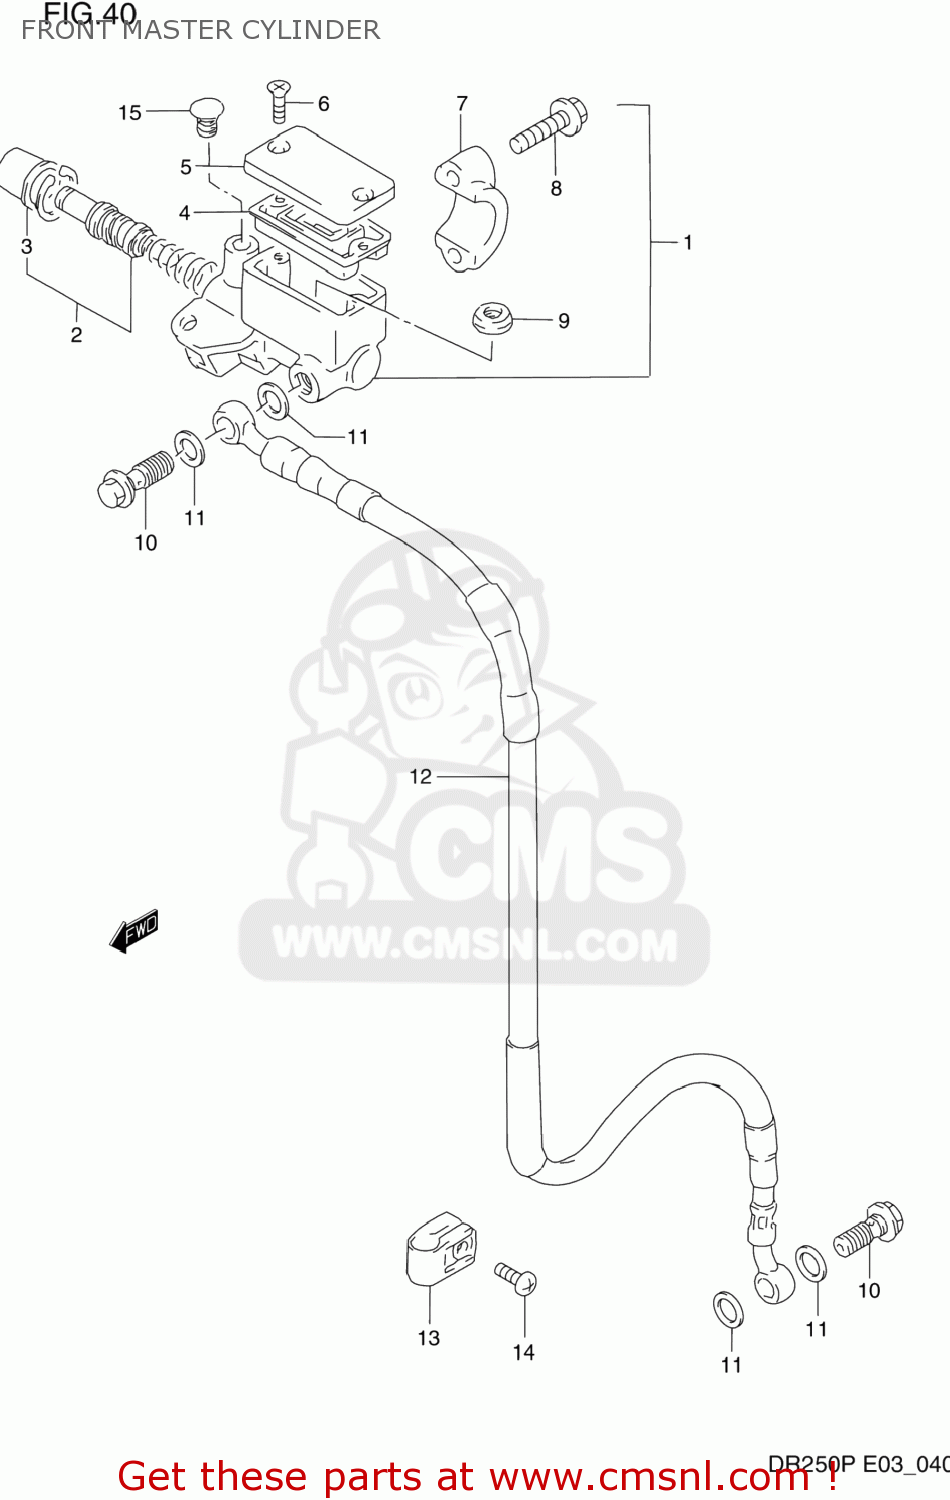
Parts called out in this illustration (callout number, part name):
1	CYLINDER ASSEMBLY,FRONT MASTER
2	PISTON & CUP SET
3	BOOT
4	DIAPHRAGM
5	CAP
6	SCREW
7	HOLDER
8	BOLT
9	SEPARATOR
10	BOLT UNION
11	WASHER(10X15X1.5)
12	HOSE,FR BRAKE
13	CLAMP,FRONT BRAKE HOSE
14	SCREW
15	CAP(OD:14)
